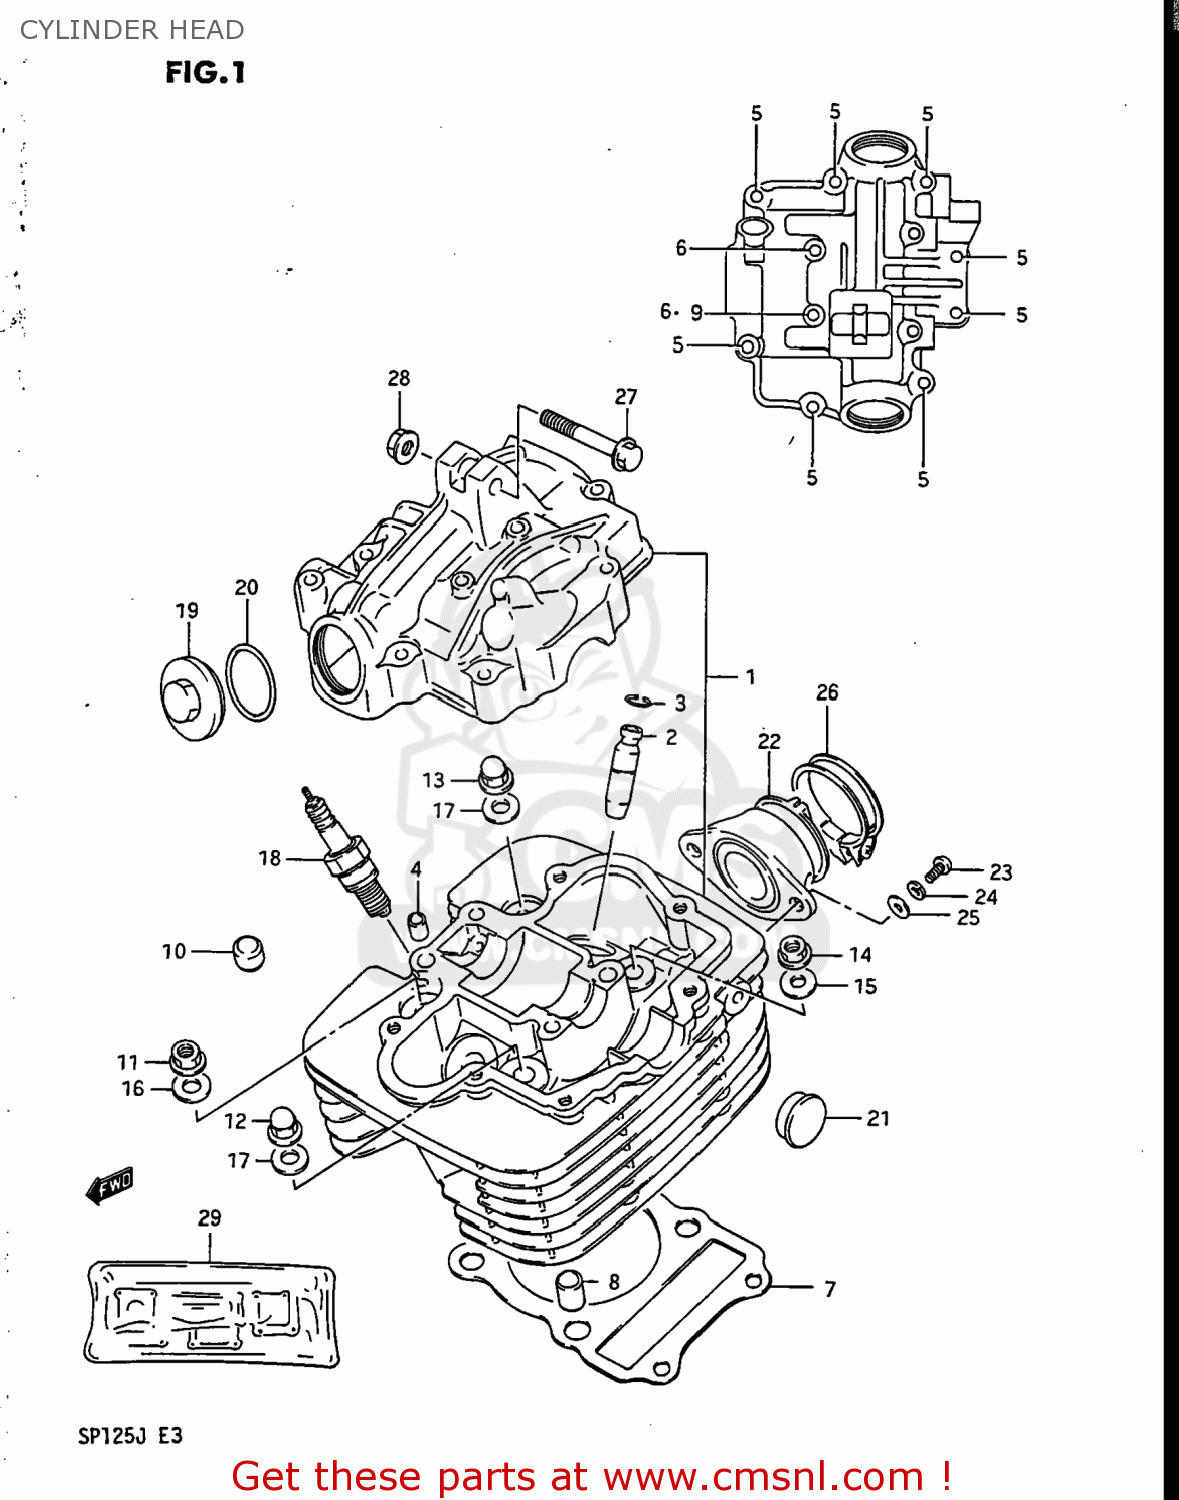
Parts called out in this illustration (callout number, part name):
1	HEAD ASSY,CYLINDER
2	GUIDE,VALVE
3	RING,SNAP
4	PIN(6.2X8X11)
5	BOLT 6X35
6	BOLT ,6X60
7	GASKET,CYLINDER HEAD (NAS)
8	PIN
9	GASKET(5.8X13X1.2) (NAS)
10	PAD,CYLINDER HEAD
11	NUT
12	NUT (8MM)
13	NUT 8MM
14	NUT
15	WASHER (8.5X19X2.3)
16	WASHER(8.5X19X2.3)
17	GASKET (NAS)
18	SPARK PLUG D8EA
19	CAP,INSPECTION
20	O RING(D:3,ID:29.5)
21	PLUG(OD:22.5)
22	PIPE,INTAKE
23	SCREW
24	WASHER,LOCK
25	WASHER
26	CLAMP
27	BOLT 8X50
28	NUT
29	GASKET SET (MCA)
